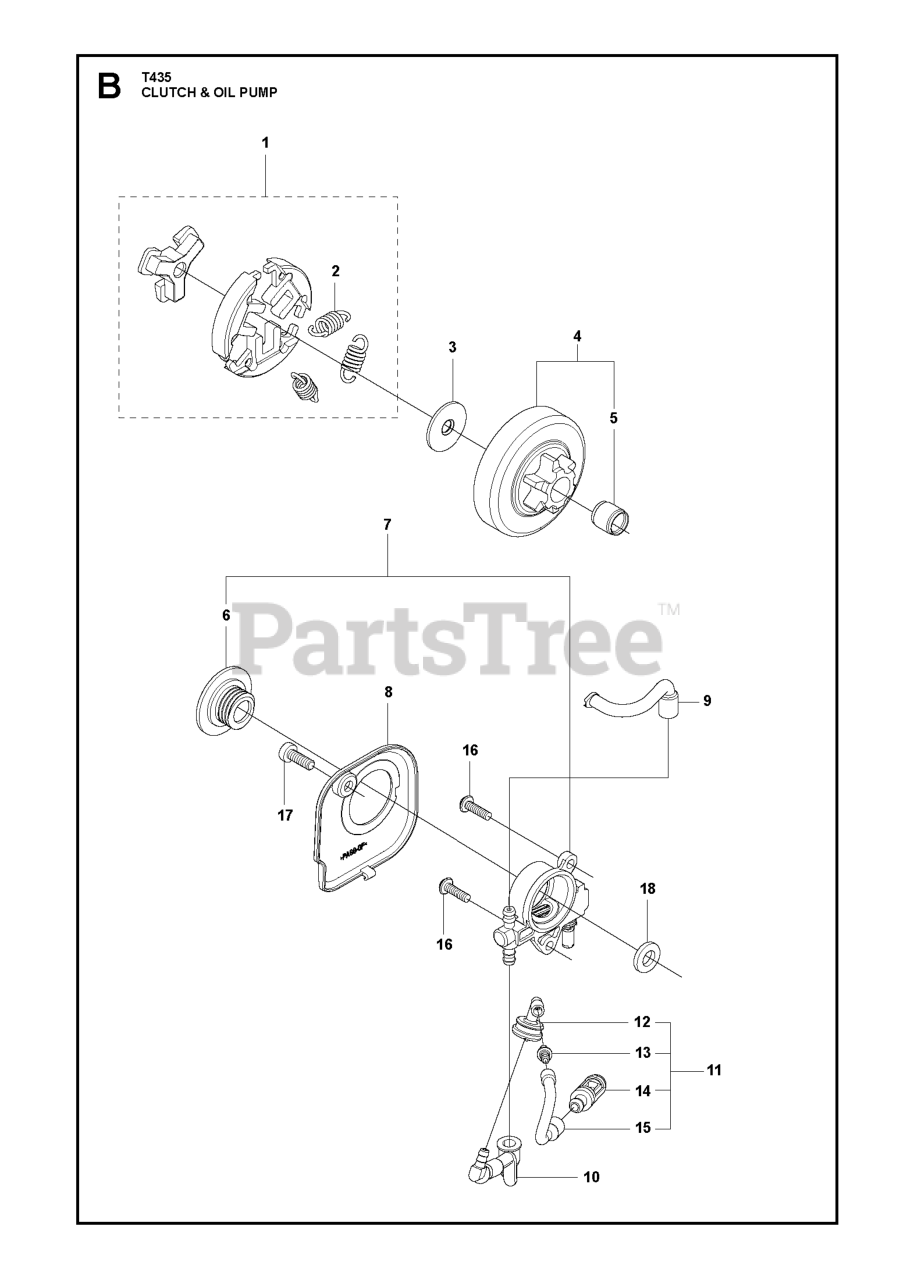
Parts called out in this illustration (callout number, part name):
1	CLUTCH-ASSY
4	DRUM
5	ROLLER BEARING
7	OIL PUMP SET(RPLS 284155112
8	COVER PUMP
10	PIPE IN COMP
11	FILTER COMPLETE
12	OIL FILTER
14	FILTER
15	PIPE (GZ3500T)
